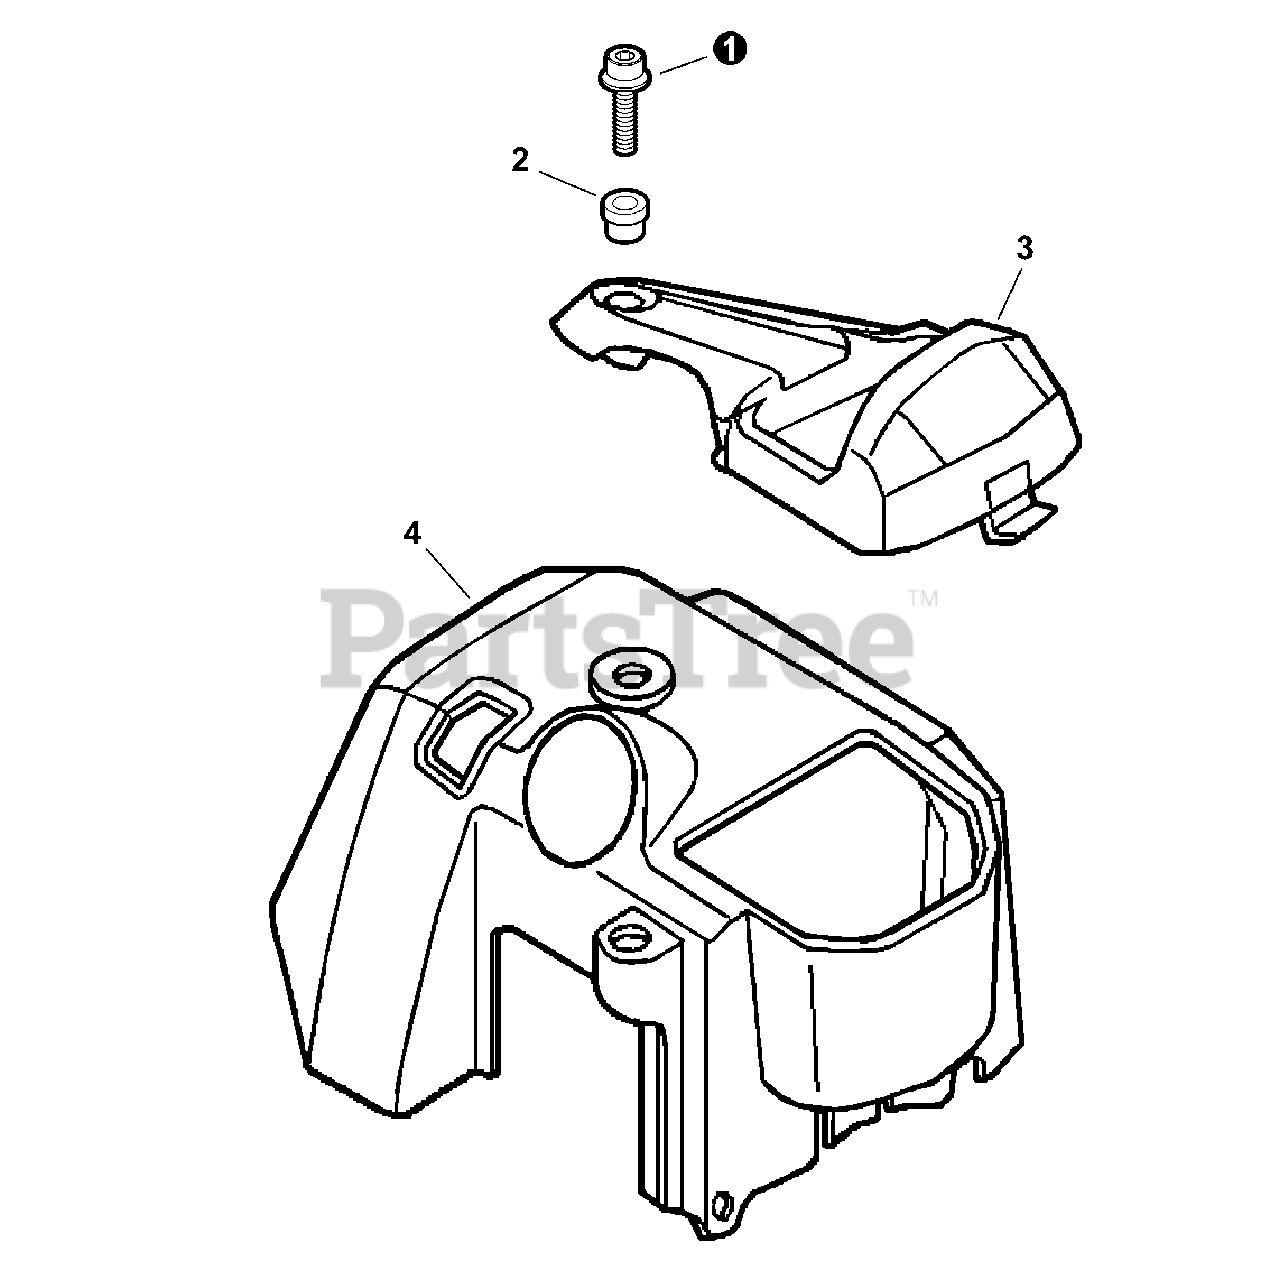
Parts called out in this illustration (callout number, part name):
1	SCREW - 5×16
2	COLLAR - 5
3	DUCT, AIR - ORANGE
4	COVER, ENGINE - ORANGE
